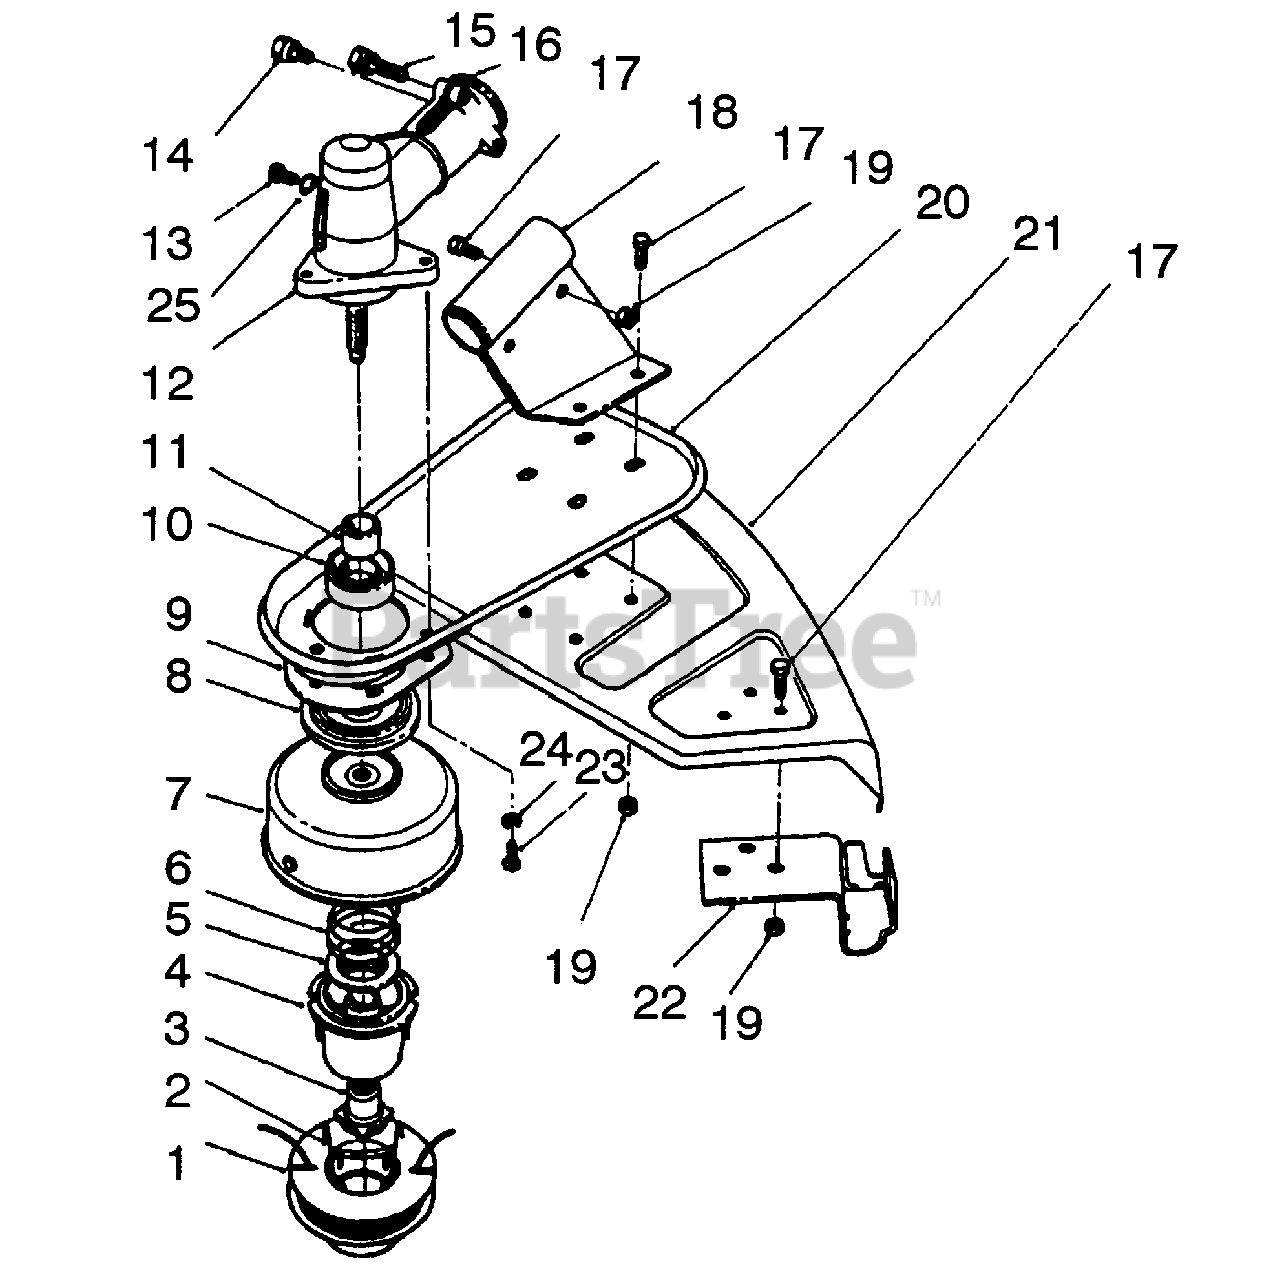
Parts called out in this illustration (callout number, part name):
1	Prewound Spool
2	Saddle-Spool Cap
3	Driver-L.H.
4	Core-Spool
7	Drum Assembly w/Eyelet
8	Cap-Dust
9	Guard-Grass Wrap
10	Seal-Oil
11	Sleeve-Spline
12	Gear Box Assembly (Incl. Ref. #10, 11 & 13-16)
13	Screw-Hex. Hd.
14	Screw-Hex. Hd.
15	Screw-Hex. Hd.
17	Screw-Hex. Hd.
18	Bracket-Shield
19	Nut-Lock
20	Support-Shield
21	Shield-Grass
22	Bracket & Knife Blade Ass'y
23	Screw-Guard
24	Washer-lock
25	Gasket-Washer
